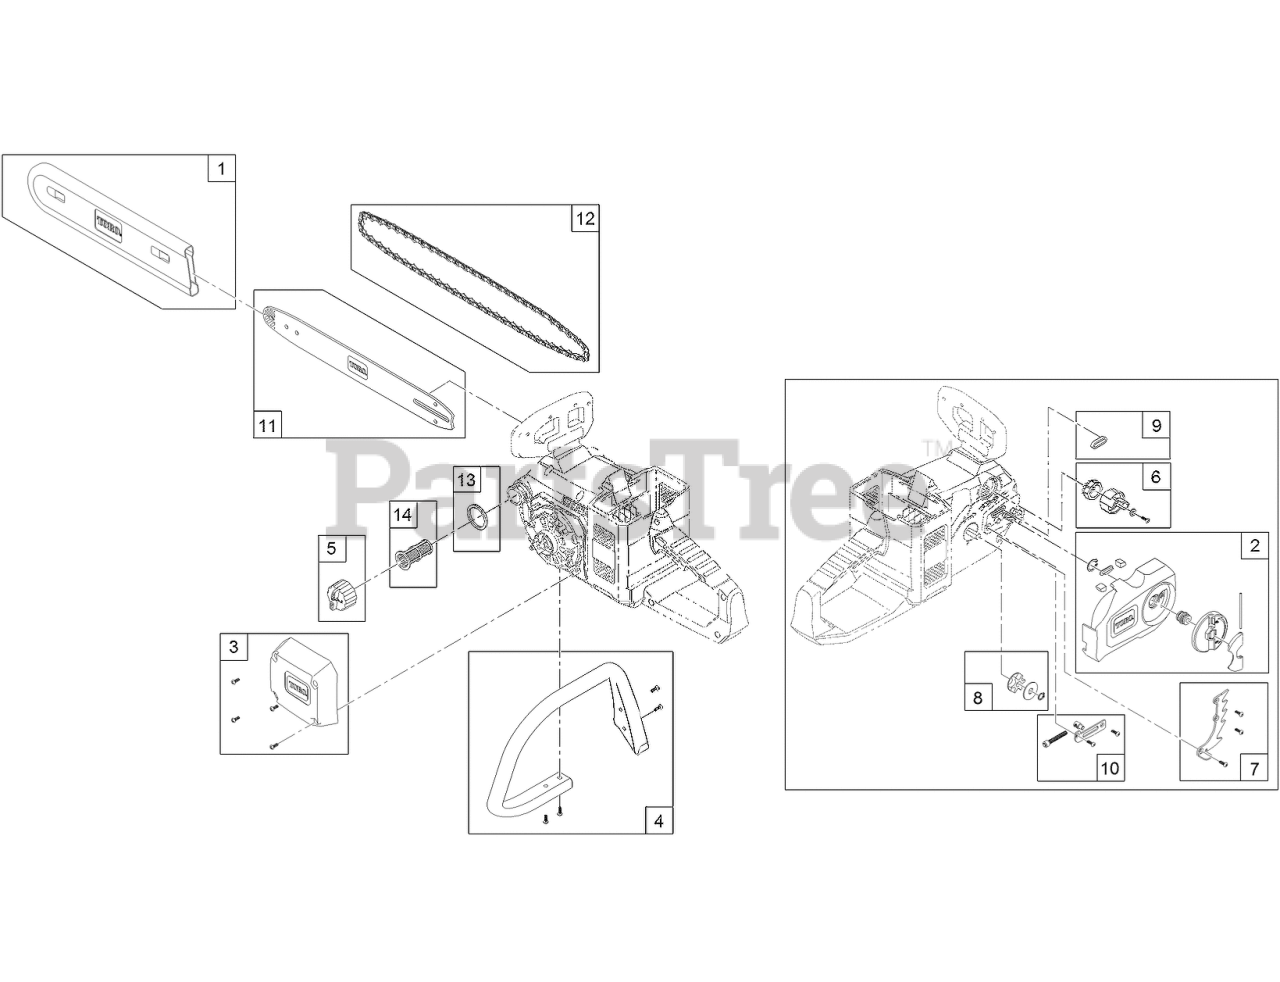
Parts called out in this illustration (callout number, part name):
1	SLEEVE-BAR/CHAIN
2	CHAIN BAR PANEL ASM
3	COVER-MOTOR
4	HANDLE
5	CAP-OIL, BAR
6	ADJUSTER KNOB WITH BAR AND CHAIN ASM
7	BUCKING TEETH BRACKET ASM
8	SPROCKET-DRIVE, CHAIN
9	GASKET-OIL, BAR/HOUSING
10	ADJUSTER BAR WITH PIN AND SCREW ASM
11	Bar-REPLACEMENT
12	CHAIN-REPLACEMENT
13	GASKET-OIL CAP, BAR
14	STRAINER-OIL, BAR
